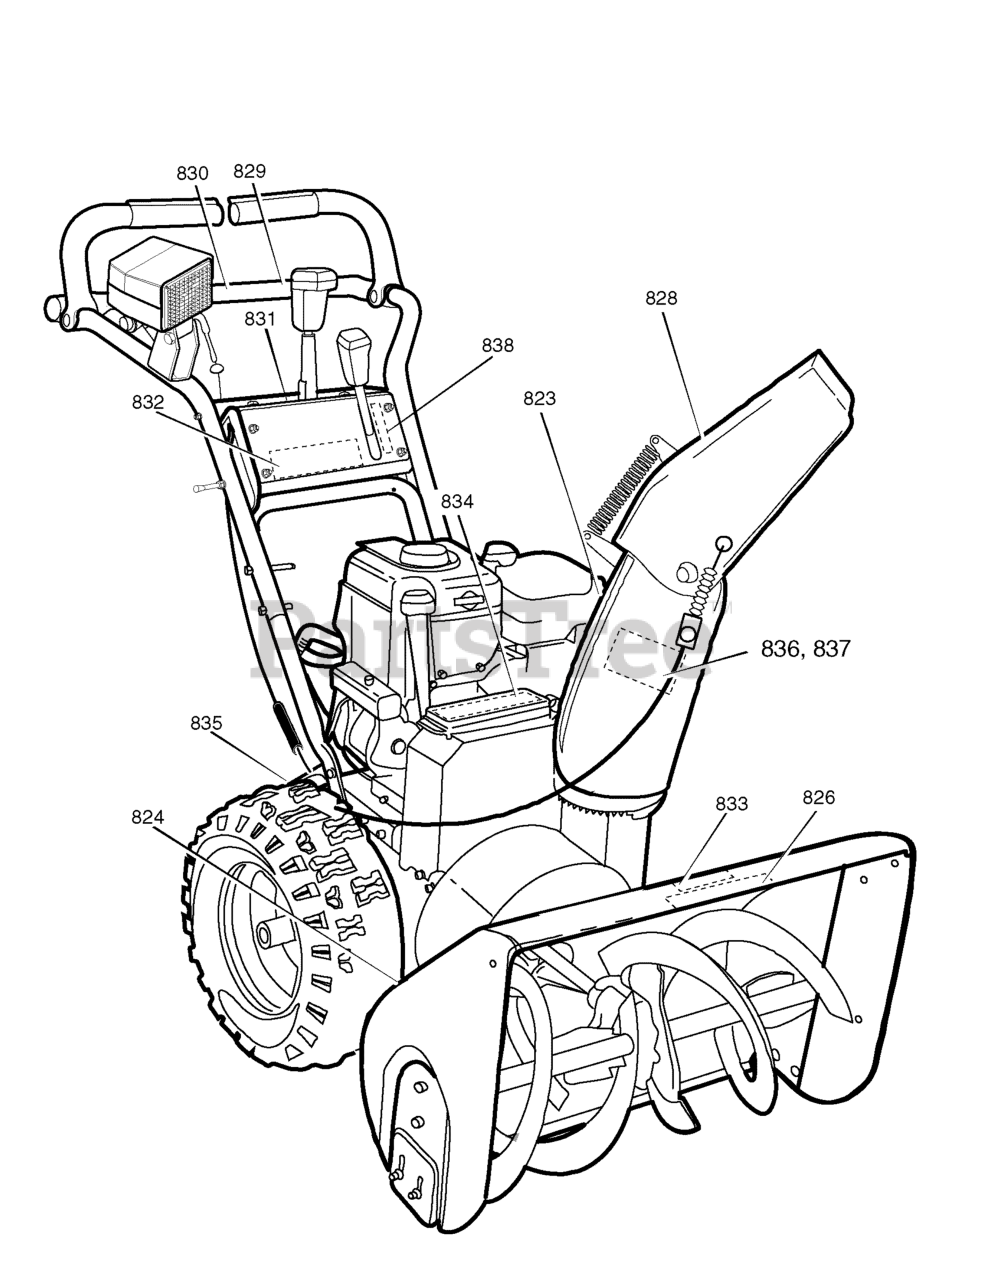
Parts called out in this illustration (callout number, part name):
823	DECAL, DANGER CHUTE HAND
824	DECAL, DANGER FOOT
826	DECAL, CRAFTSMAN 1550/30
828	DECAL, THROWN OBJECTS
829	DECAL, DRIVE CLUTCH
830	DECAL, AUGER CLUTCH
831	DECAL, GEAR SELECTOR
832	DECAL, CRAFTSMAN
833	DECAL, CLEAN & CLEAR BRUSH
834	DECAL, TOOLBOX INFORMATION
835	DECAL, ID PLATE
836	DECAL, POWER 2 STEER, ENGLISH
837	DECAL, POWER 2 STEER, FRENCH
838	DECAL, REMOTE CHUTE FR/EN
